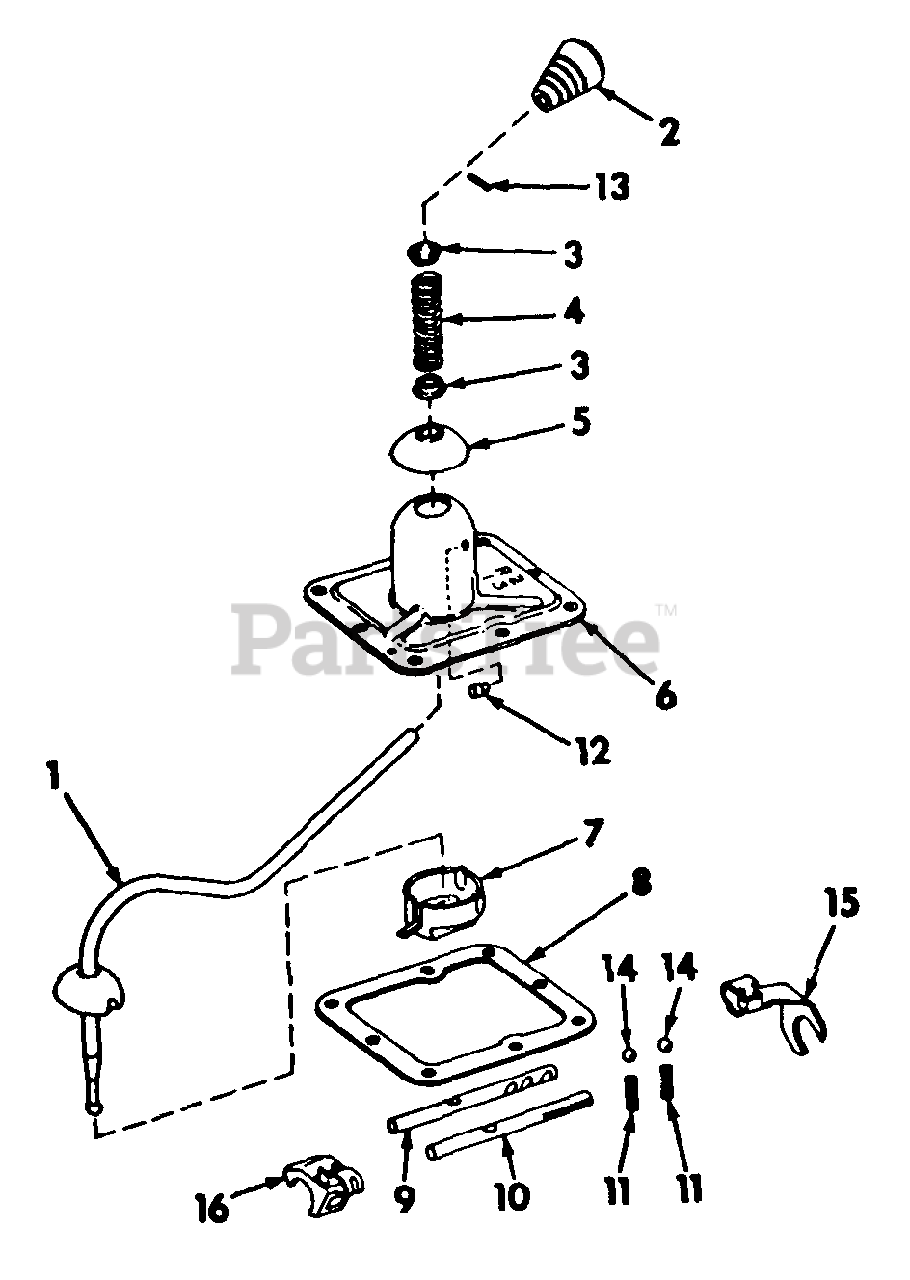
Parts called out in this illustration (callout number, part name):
1	LEVER ASSEMBLY, GEAR SHIFT
2	KNOB SHIFT HANDLE
3	RETAINER, SPRING
4	SPRING, SHIFT LEVER
5	SHIELD, SHIFT LEVER
6	HOUSING ASSY, GEAR SHIFT LEVER
7	GUIDE, LEVER
8	GASKET, LEVER HOUSING
9	ROD, 2ND & 3RD GEAR SHIFTER
10	ROD, 1ST & REVERSE GEAR SHIFTER
11	SPRING, SHIFTER POPPET
12	PIN, LEVER SWIVEL STOP
13	PIN, SPRING RETAINER
14	BALL, 3/8 CR STL
15	PACKAGE, 2ND & 3RD SPEED SHIFTER FORK
